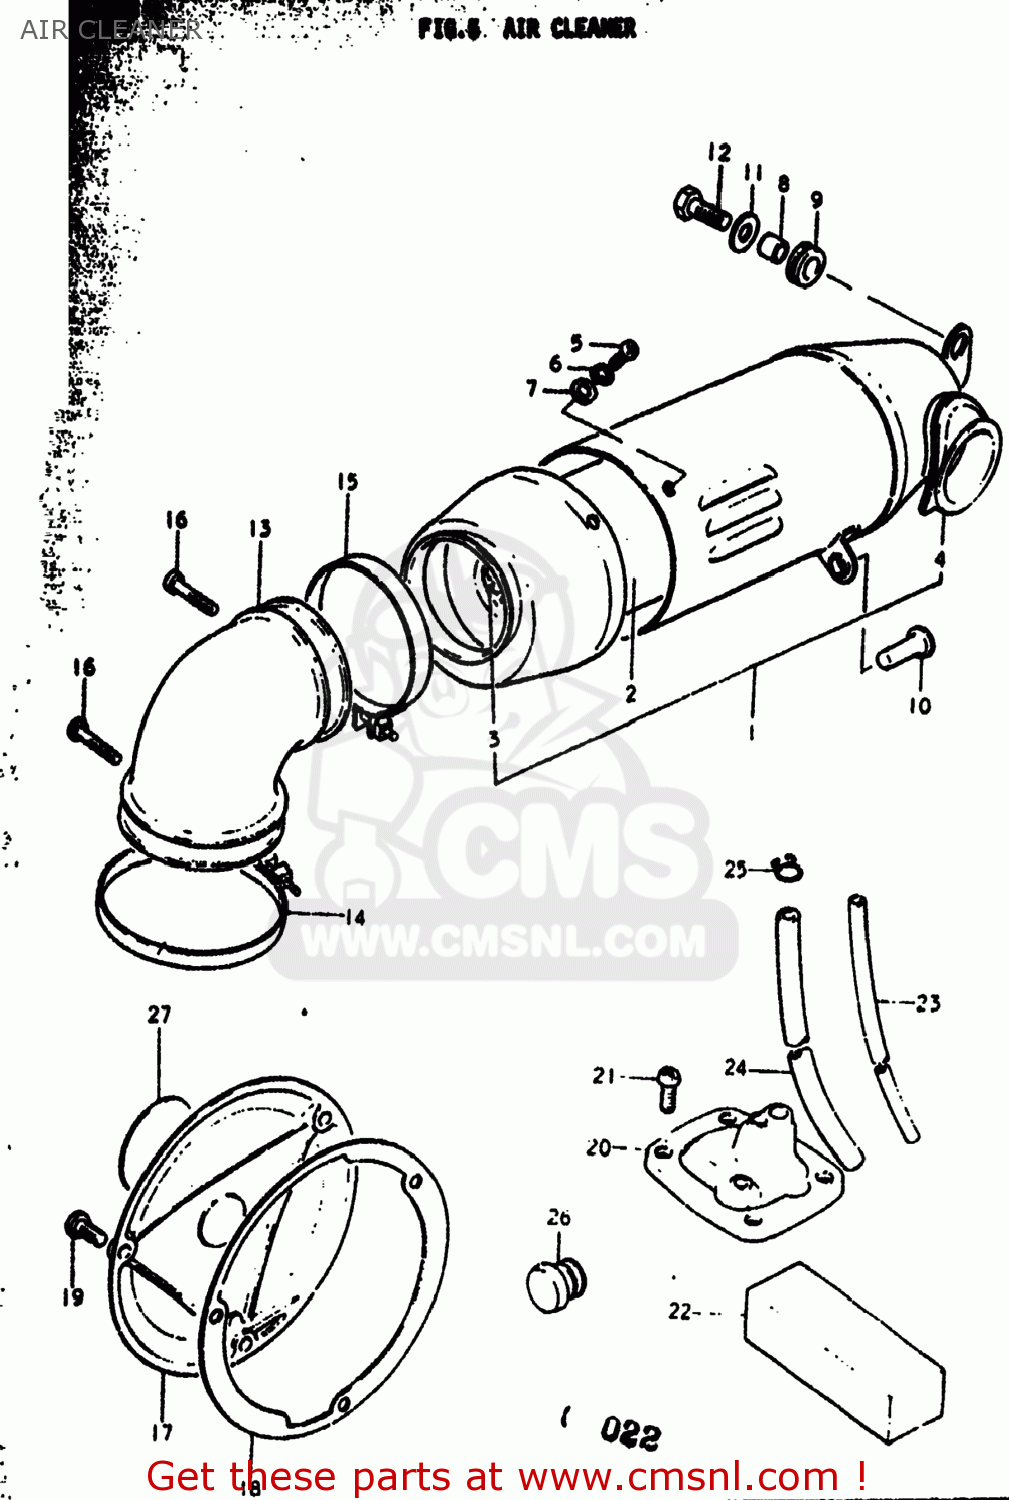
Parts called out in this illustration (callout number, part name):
1	CLEANER ASSEMBLY,AIR
2	FILTER ASSY
3	FILTER,AIR CLEANER
4	PIPE,AIR CLEANER INLET
5	SCREW
6	LOCK WASHER
7	WASHER
8	SPACER (7X9X7)
9	CUSHION
10	CUSHION
11	WASHER (6.5X20X1.2)
12	BOLT
13	TUBE,AIR CLEANER OUTLET
14	CLAMP
15	CLAMP
16	SCREW
17	CAP,CARBURETOR INSPECTION
18	GASKET,CARB INSPECTION CAP (NAS)
19	SCREW
20	COVER,CARBURETOR TOP
21	SCREW
22	SEAL,DUST
23	HOSE
24	HOSE
25	CLIP
26	Plug
27	EMBLEM,CARB INSPECTION CAP
